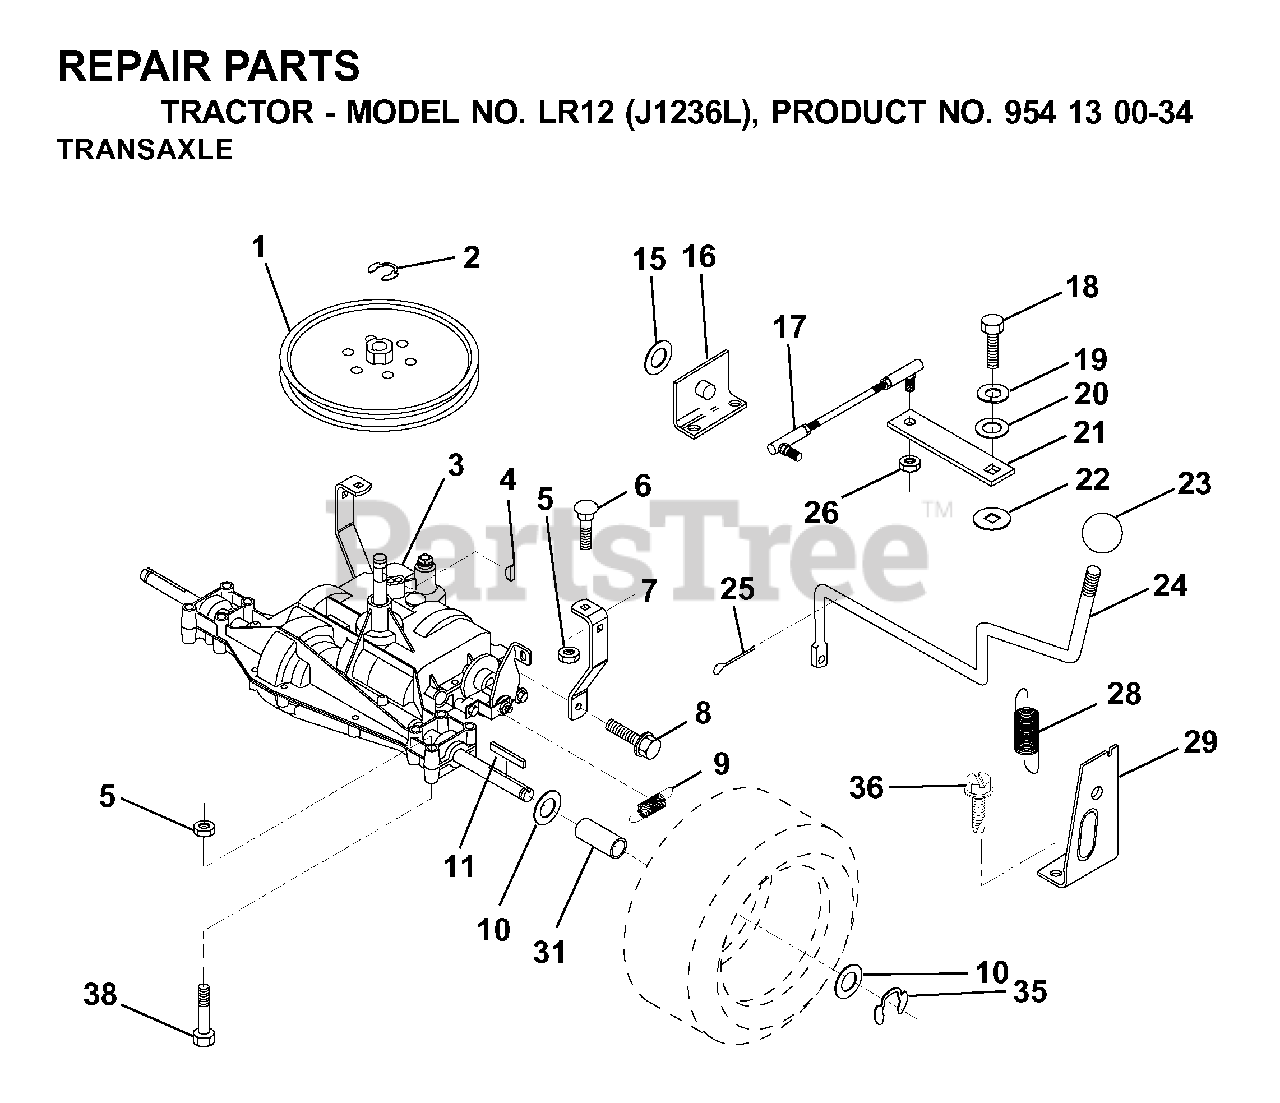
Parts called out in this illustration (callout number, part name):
2	RETAINING RING LT
5	LOCKNUT
6	BOLT
7	STRAP,TORQUE
8	SCREW 5/16"
9	SPRING,BRAKE RETURN
11	SQUARE KEY
15	WASHER
16	SUPT, HDLE SHT LH
18	BOLT 1/4-28X3/4
19	LOCKWASHER
20	WASHER LT
22	WASH-SHFT PLT LT
23	KNOB.DUCKHEAD.1/2
24	ROD, SHIFT
25	PIN COTTER
26	LOCKNUT
28	SPRING.EXTENSION
29	SUPPORT HANDLE SHAFT RH
31	SPACER AXLE
35	E-RING LT
36	SCREW
